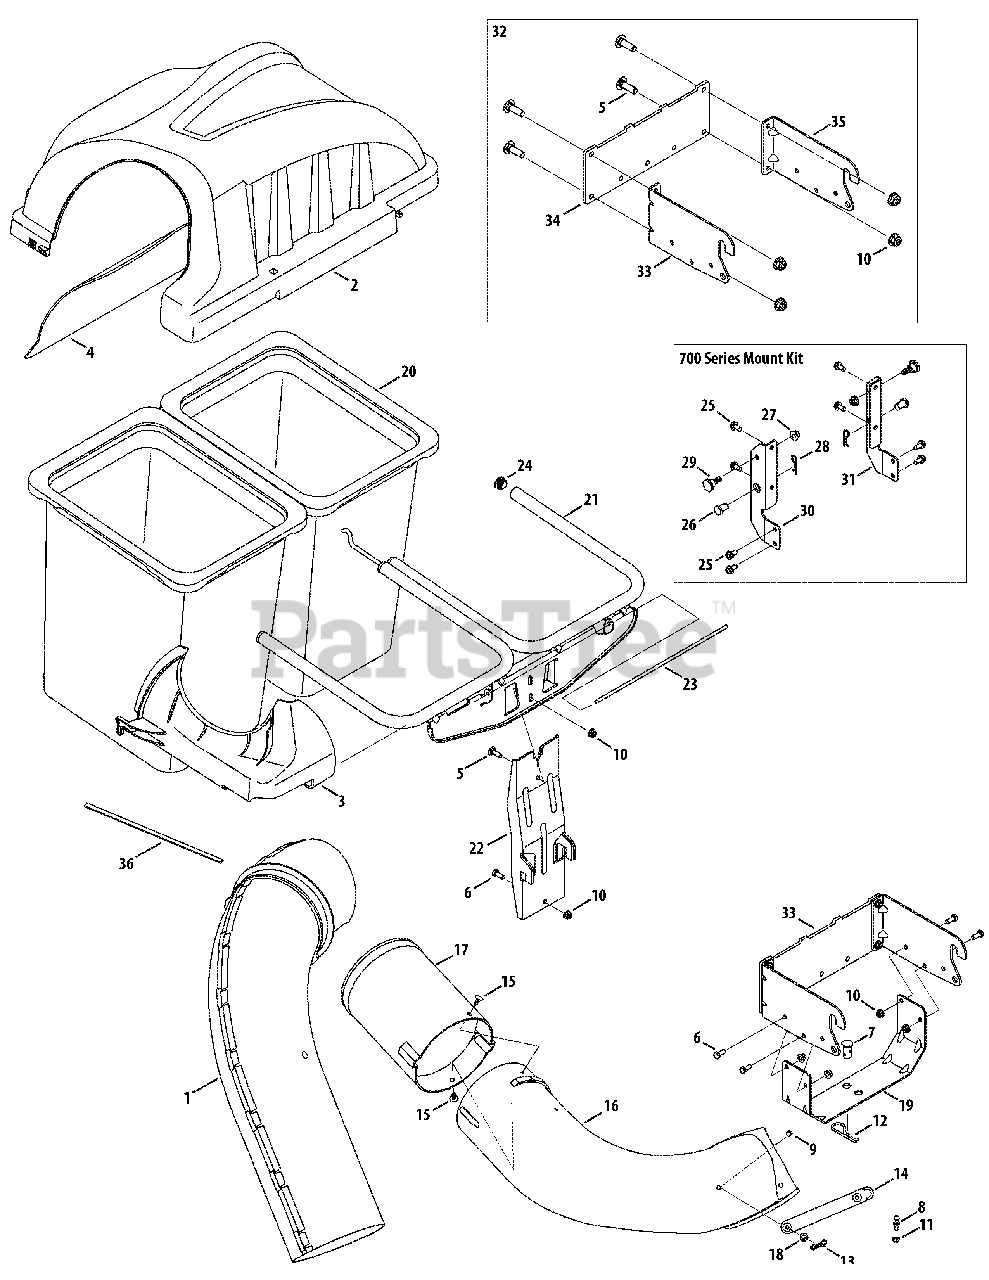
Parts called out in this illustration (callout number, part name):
1	Upper Chute Assembly
2	Double Bagger Cover Assembly
3	Upper Chute Support
4	Bagger Cover Screen
5	Carriage Screw, 5/16-18 x 1.00"
6	Hex Head Screw, 5/16-18 x .75"
7	Clevis Pin, .62" Dia.
8	Grass-catcher Pin, 1/4-20
9	Clevis Pin, 5/16 x .75 Lg.
10	Flange Lock Nut, 5/16-18
11	Flange Lock Nut, 1/4-20
12	Internal Cotter Pin, .148 x 3.00
13	Bow-Tie Cotter Pin, 72
14	Chute Strap, 6.00 Lg.
15	Ratchet Clip, .250
16	Discharge Chute Elbow, 38"/42"
17	Bagger Chute Adapter, 7 In.
18	Flat Washer, .344 x .62 x .033
19	Universal Bracket Support
20	Grass-bag Assembly
21	Double Bag Support Assembly
22	Vertical Support Bracket
23	Cover Hinge Pin
24	End Plug
25	Tap Screw, 5/16-18 x .750
26	Clevis Pin, .50 x .78 Lg.
27	Flange Lock Nut, 3/8-16
28	Click Pin, .092 x 1.64 Lg.
29	Shoulder Screw, .625 x .412
30	Mounting Bracket, RH
31	Mounting Bracket, LH
32	Hitch Bracket Assembly
33	Hitch Bracket, RH
34	Rear Attachment Bracket
35	Hitch Bracket, LH
36	Self-Adhesive Foam Strip
